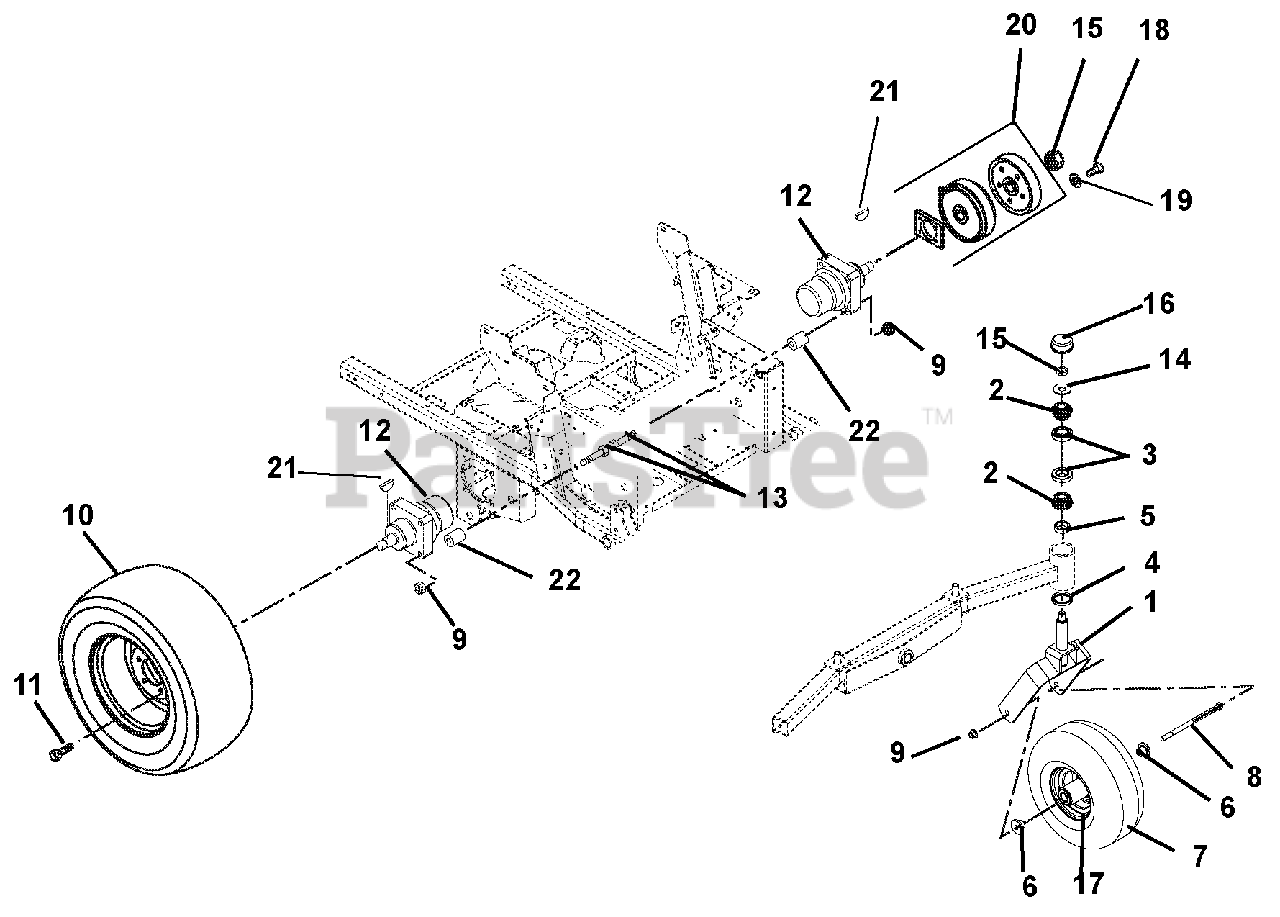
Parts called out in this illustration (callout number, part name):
1	Fork, Front
2	Bearing, Cone
3	Bearing, Cup 2.328 x .465
4	Bearing Seal 1.75 x 2.332 x .312
5	Spacer, 1.258ID x 1.750OD x .550
6	Spacer, Wheel
7	Wheel/Tire Assembly, 15 x 6-6, Smooth
7	Tire, 15 x 6-6, Smooth
8	Bolt, Hex .50-13 x 9.00 Grade 5
9	Nut-Locking-Top-Flange .50-13
10	Tire/Wheel Assembly, 24 x 11.50-12
10	Tire, 24 x 11.50-12
11	Bolt, Lug .50-20 x 1.38
12	Wheel Motor, Parker
13	Bolt, Wheel Motor .50-13 x 2.75 (992212)
13	Bolt, Wheel Motor .50-13 x 5.00 (992210, 213, 217)
14	Washer, Flat Steel, .812 x 2.00 x .148
15	Nut-Jam Ctrlk .75-16 Ywzc
16	Cap, Dust
17	Bearing, 25mm I.D. x 52mm OD x 15mm
18	Bolt, Hex .31-18 x 1.50 Grade 8 EP30
19	Waher, Lock .31 x .078
20	Kit, Parking Brake Service
21	Key, Woodruff .31 x 1.00
22	Bushing, .513 x .748 x 2.129 (992210, 213, 217)
